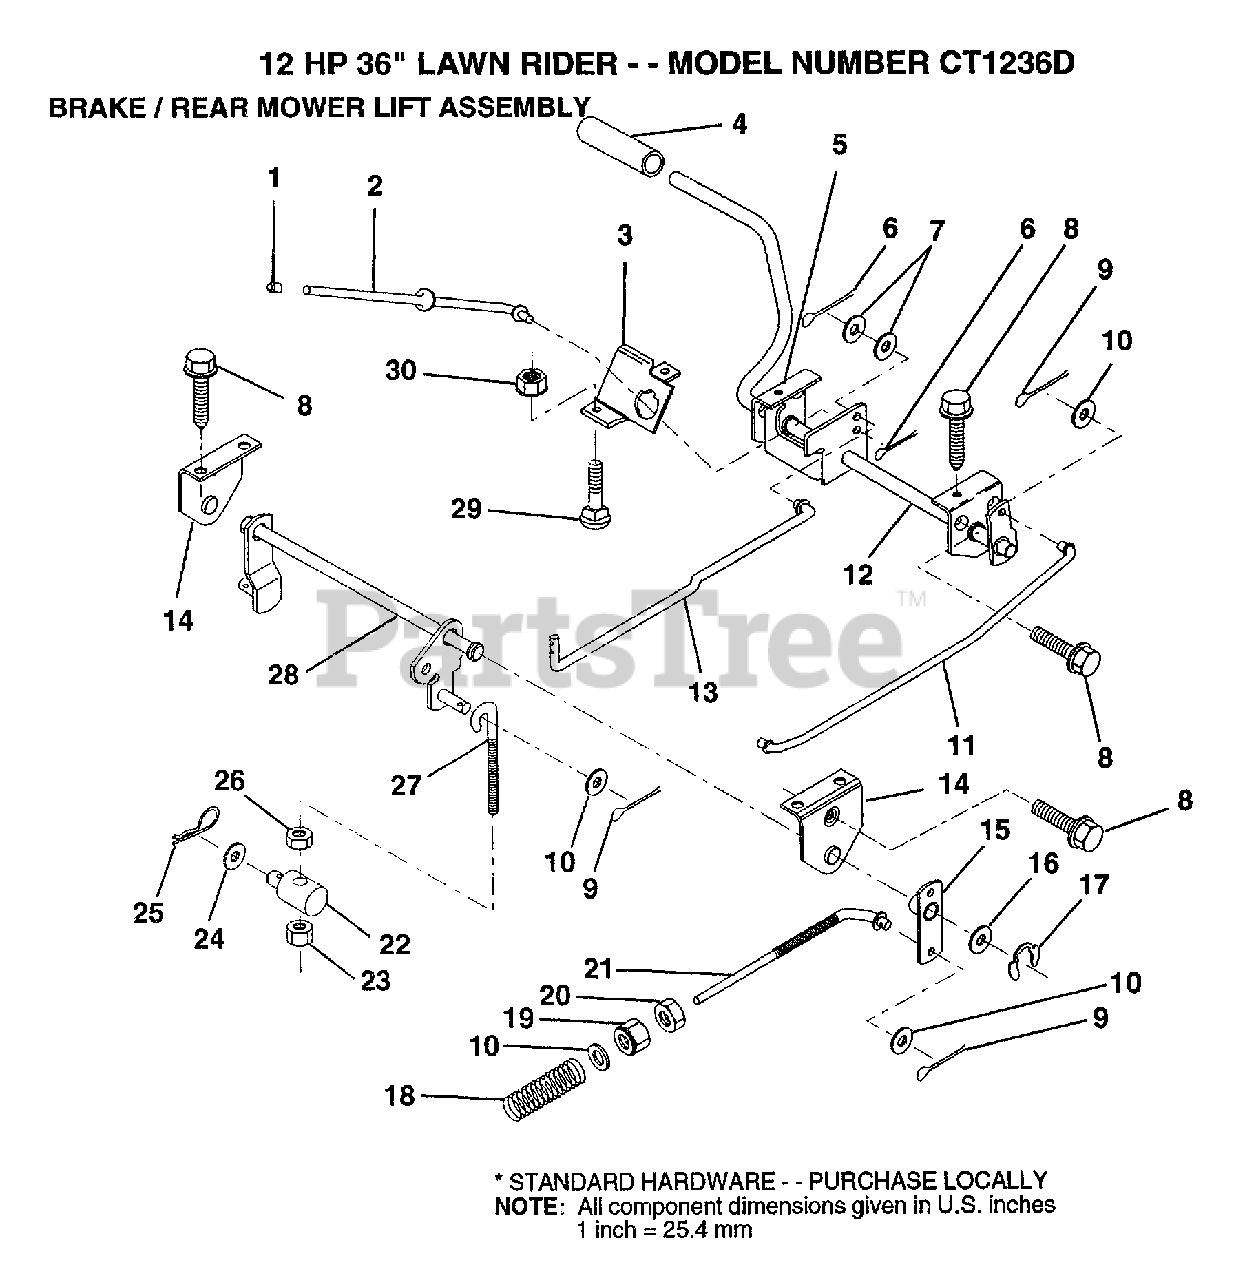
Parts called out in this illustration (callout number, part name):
1	PLUNGER CAP T
2	"ROD,PARK BRAKE"
3	"BRKT,PARK BRAKE"
4	PEDAL COVER T
5	"BRKT,CLU PEDAL LH"
7	WASHER
8	SCREW LT
9	COTTER PIN
10	WASHER
11	"ROD,FRT BRAKE"
13	"ROD,CLUTCH"
14	"BRKT,LIFT SHAFT"
15	BRAKE PIVOT ARM
16	WASHER T
17	KLIP RING
18	SPRING ROD LT
19	NUT
20	NUT
24	WASHER
25	SPRING.RETAINER
26	LOCKNUT
27	"LINK, MOWER REAR"
